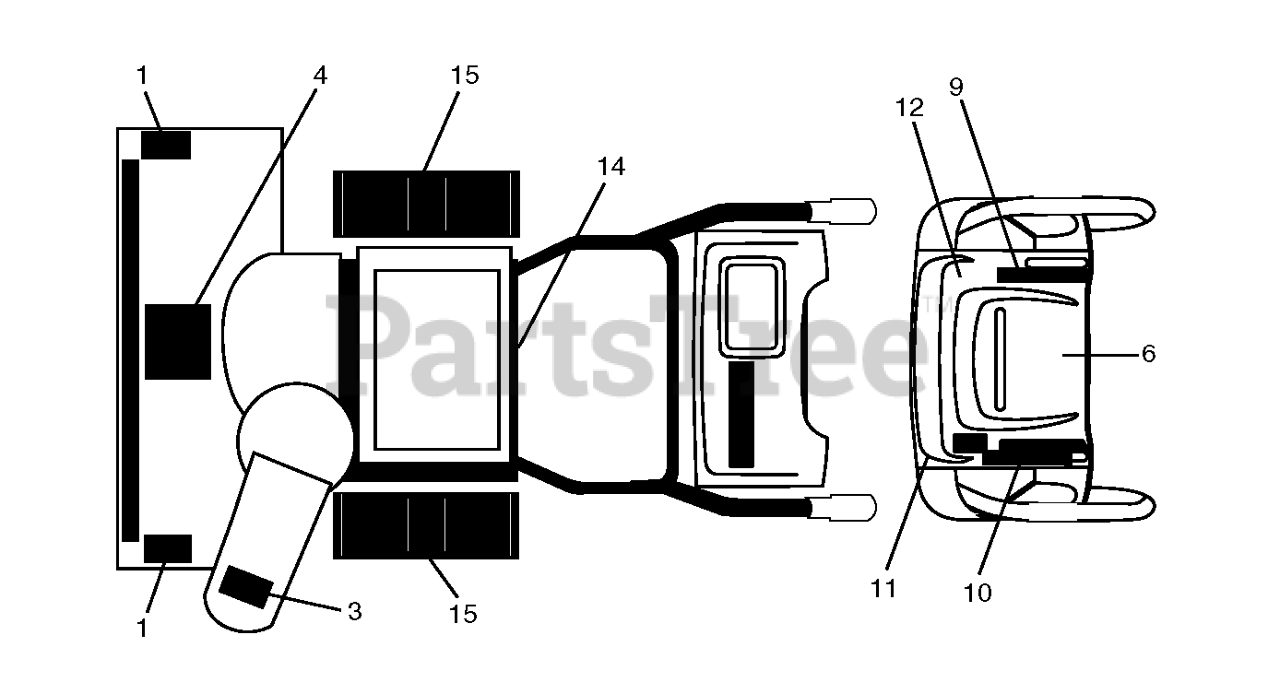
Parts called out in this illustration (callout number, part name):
1	DECAL.AUGER.SAFETY.
3	DECAL.CHUTE.SAFETY.
4	DECAL.AUGER."
9	DECAL.CONS.RT.SPD/LEV/PWRST.
10	DECAL,LHTRIGGER
11	DECAL,HEIGHTADJUST
12	DECAL.CONSOLE.HAND.WARMER
14	DECAL.FENDER
15	DECAL.BELT.GUARD.
